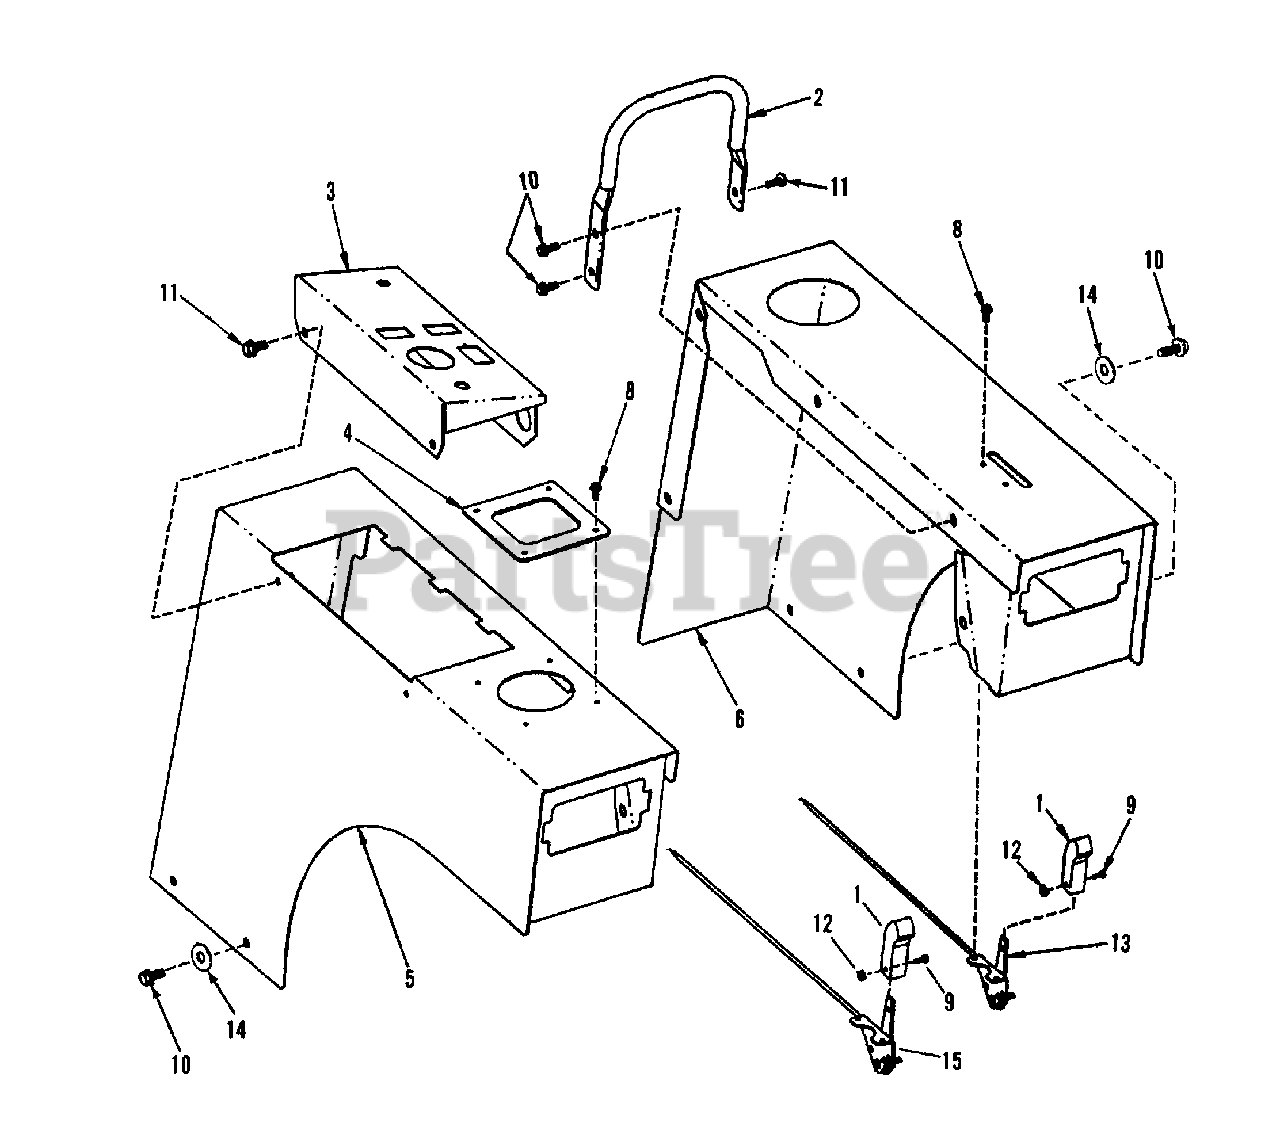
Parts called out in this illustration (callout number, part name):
1	LEVER, Throttle Control
2	HANDLE, 5/8" Tubing
3	PANEL, Instrument
4	PLATE, Joystick Control
5	FENDER, Right Hand
6	FENDER, Left Hand (21 HP Diesel Engine)
6	FENDER, Left Hand (23 HP Gas Engine)
8	SCREW, #10-24 x 1/2" Hex Washer Self-Tap (Torx)
9	SCREW, #8-32 x 3/8" Machine
10	SCREW, 5/16-18 x 5/8" Hex Self-Tapping
11	SCREW, 1/4-20 x 5/8" Hex Flange Lock
12	NUT, #8-32 Hex
13	CONTROL, Engine Speed 62.0" (21 HP Diesel Engine)
13	CONTROL, Engine Speed 31.0" (23 HP Gas Engine)
14	WASHER, 5/16 I.D. Flat
15	CONTROL, Choke 62.87" (23 HP Gas Engine)
